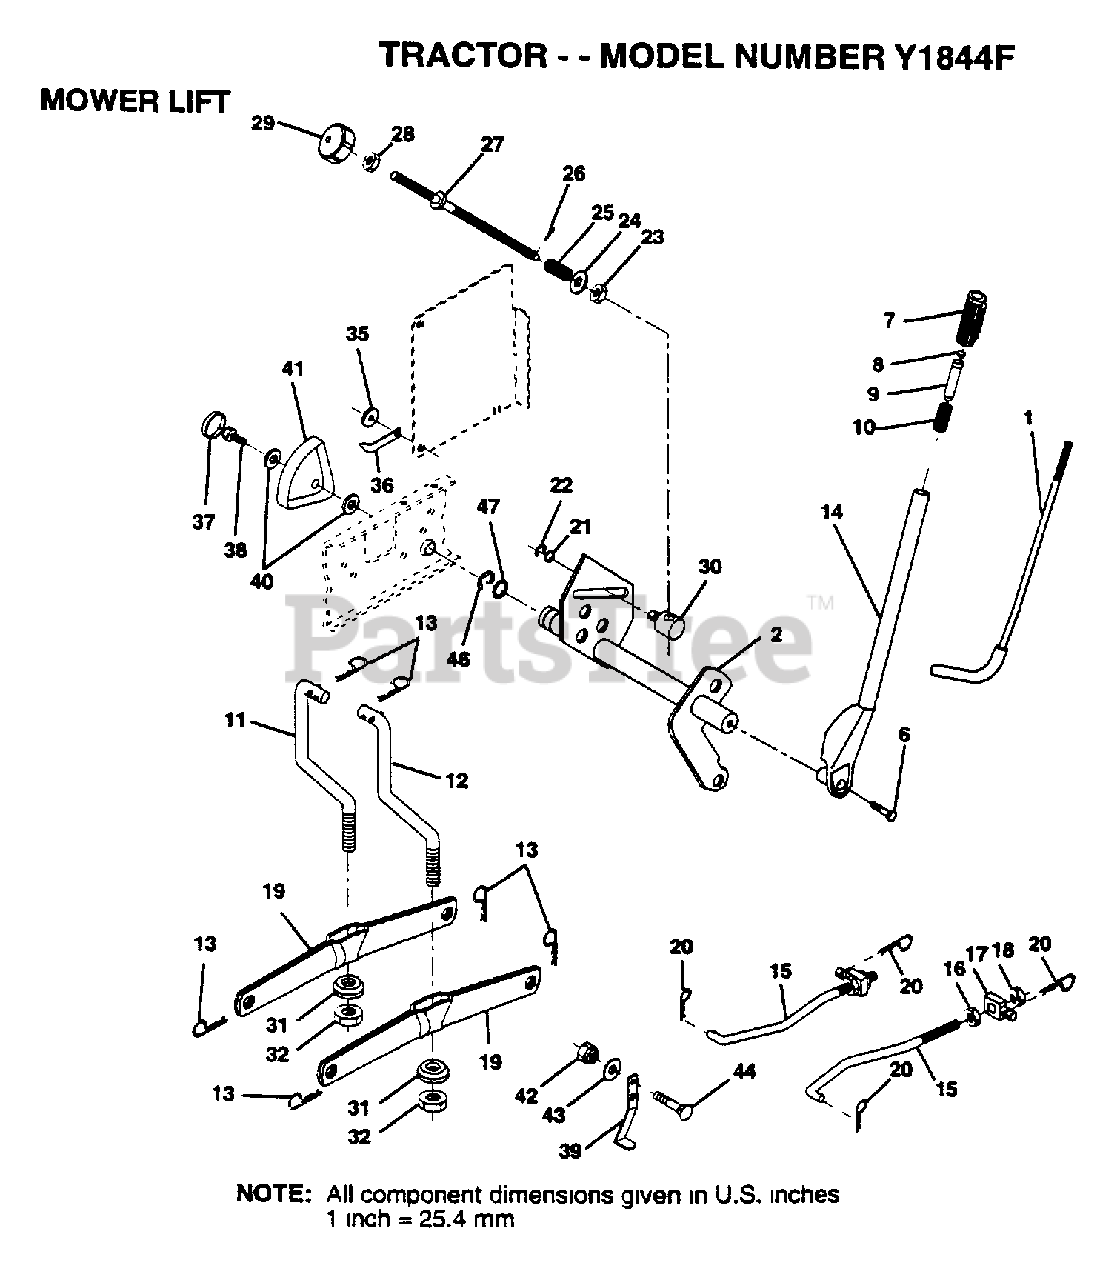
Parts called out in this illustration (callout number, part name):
1	LEVER ROD LT
2	SHAFT LIFT W/IND
6	"BOLT,HEX"
7	GRIP
10	SPRING T
11	LINK.LIFT.LH.GTV
12	LINK.LIFT.RH.GTV.
15	LINK.FRONT
16	NUT
17	TRUNION
18	NUT.LK.W/WSH.1/2.
19	ARM SUSP REAR
20	RETAINER.SPRING
21	WASHER
22	KLIP RING
23	NUT T
24	WASHER
25	SPRING T
27	ROD LIFT LT
28	NUT
29	KNOB INF 3/8-16
30	TRUNION LT
31	BEARING PVT LH
32	NUT.CROWNLOCK.3/8
35	WASHER T
36	POINTER HGT IND
37	"PLUG,HOLE"
38	SCREW
39	STOP.OVER.CENTER
40	WASHER
41	HEIGHT INDICATOR
43	WASHER GT
44	BOLT
46	E-RING
47	WASHER
